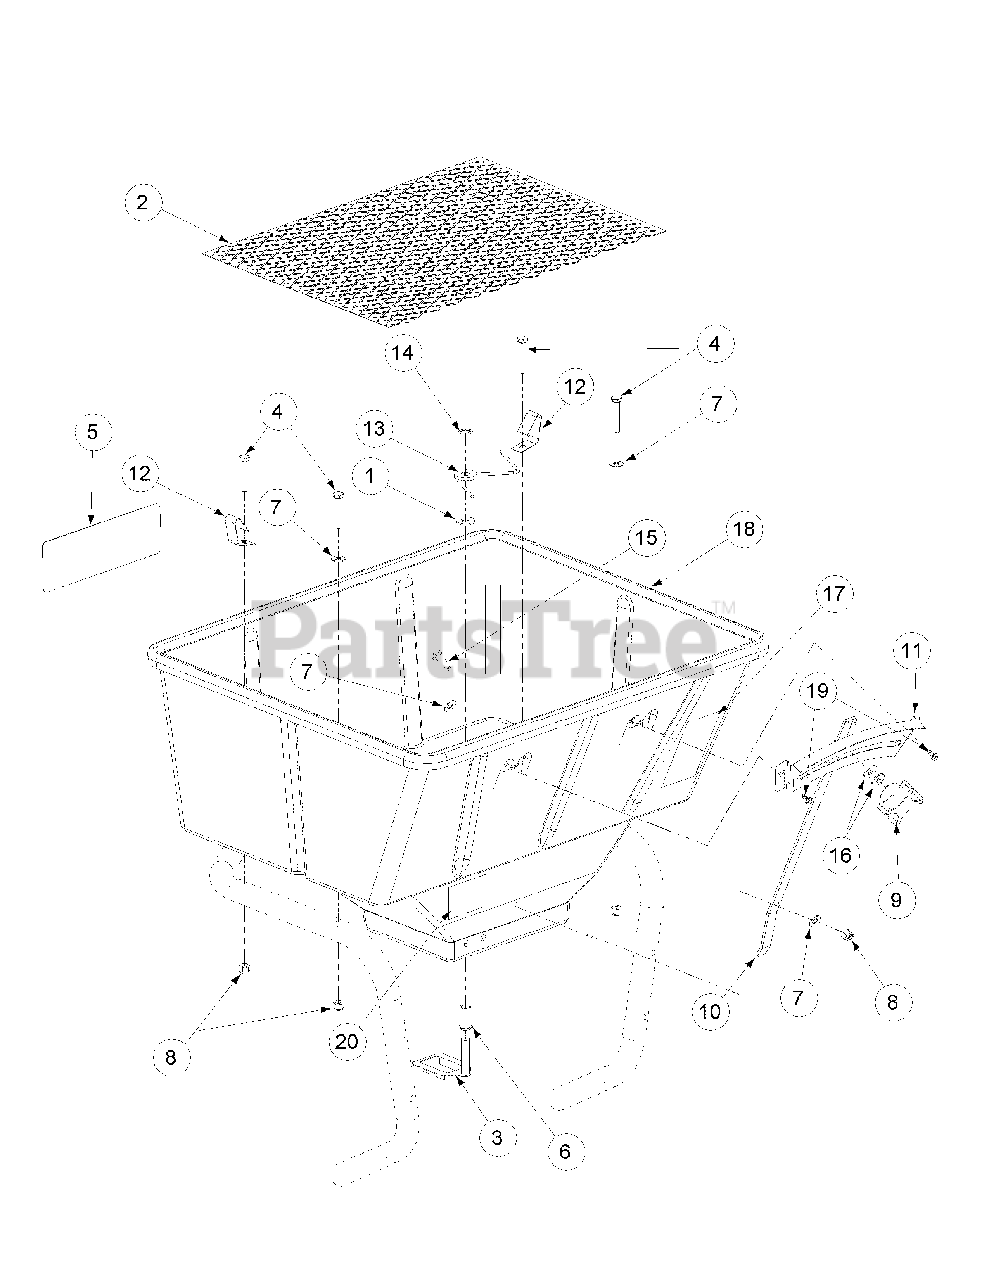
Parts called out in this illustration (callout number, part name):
1	Nylon Flat Washer, 3/8
2	Screen, SS
3	Agitator Assembly
4	Hex Cap Screw, 1/4-20, 1.50
5	CCC Decal, 2-3/8 x 7-1/8
6	Agitator Shaft Bearing
7	Flat Washer, 1/4"
8	Nylock Nut, 1/4-20
9	Control Rate Knob
10	Control Arm Rate
11	Control Plate Rate
12	Screen Clip
13	Agitator Arm Assembly
14	3/8 Retainer Spring Clip
15	Screw, 1/4-20 x .75
16	Nylon Flat Washer, 1/4
17	4" x 2" Vinyl Decal
18	Hopper Yellow
19	Index Washer Hex Screw, #8 x 3/8
20	Decal, USA
